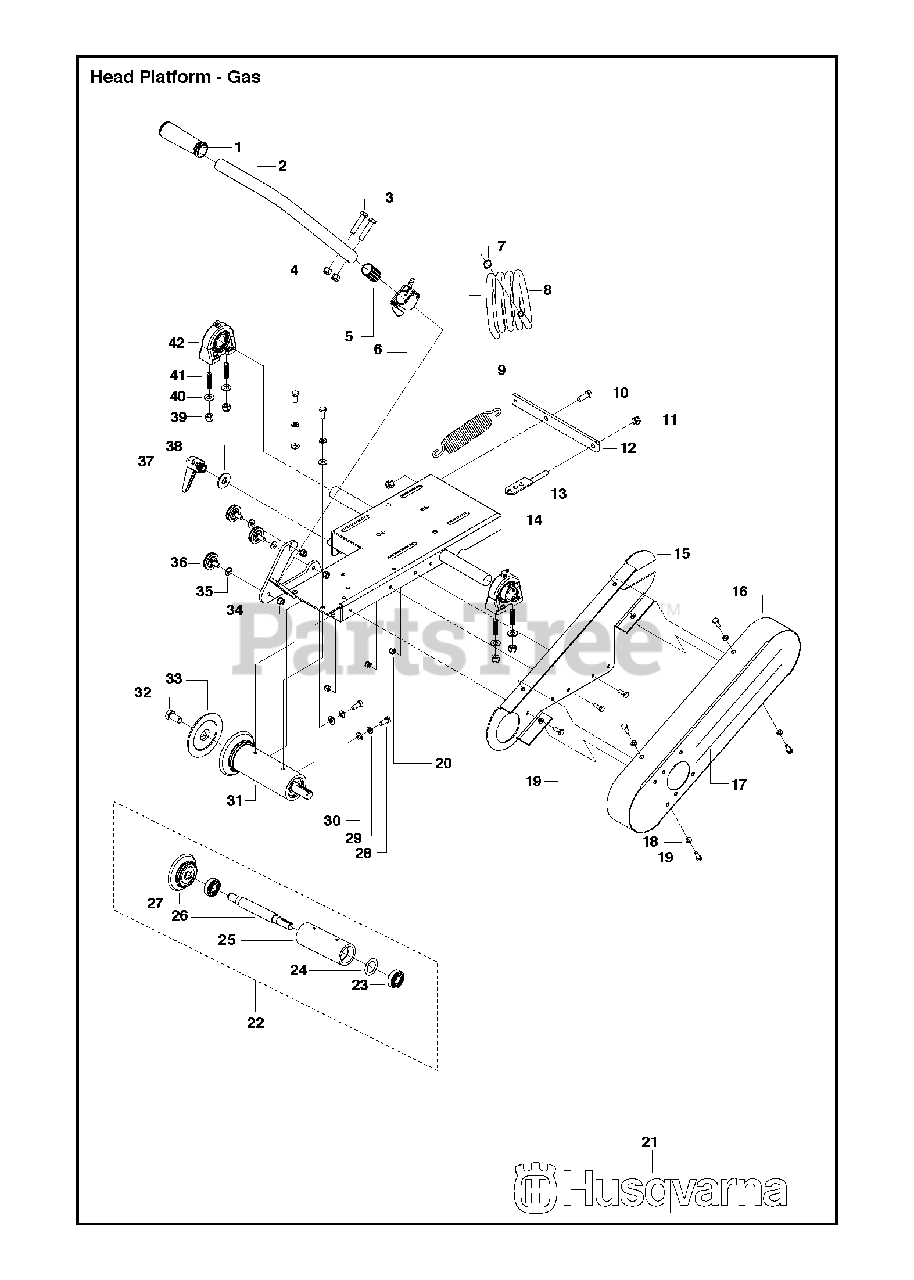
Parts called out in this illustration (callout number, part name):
4	NUT
11	NUT
20	NUT
29	WASHER
30	WASHER
35	WASHER
36	FS700/2/900/2 WHEEL SUR/BEARIN
39	NUT
40	WASHER
